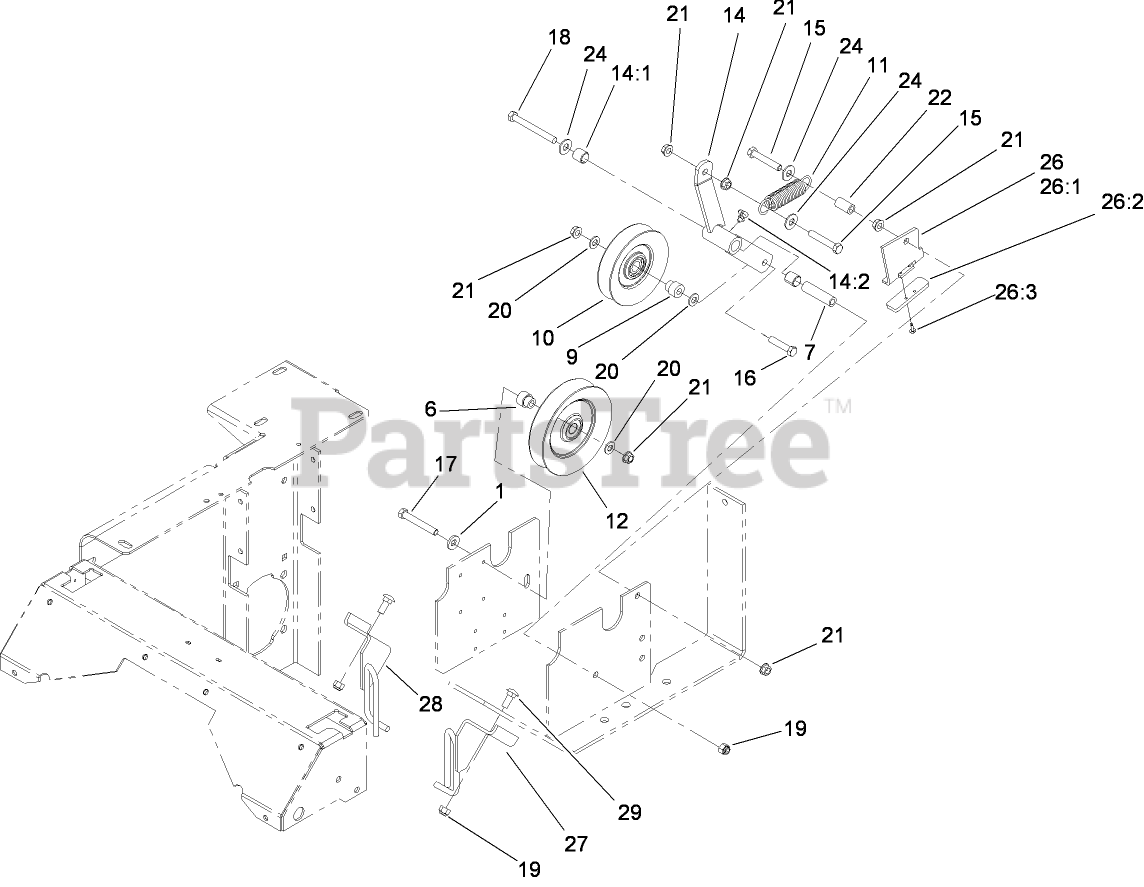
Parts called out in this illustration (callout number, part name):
1	WASHER-BELLEVILLE
6	Bushing-Idler
7	BUSHING-PIVOT, IDLER
9	BUSHING-IDLER
10	Idler
11	SPRING-EXTENSION
12	PULLEY-IDLER
14	Arm ASM
14:1	SLEEVE-BEARING
14:2	FITTING-GREASE, 90 DEG
15	SCREW-HH
16	SCREW-HH
17	SCREW-HH
18	SCREW-HH
19	NUT-LOCK, NI
20	WASHER-FLAT
21	NUT-HHF, WHIZ
22	SPACER
24	WASHER-FLAT
26	Travel Limiter ASM
26:1	Plate-Limiter, Pulley
26:2	PAD-BUMPER
26:3	RIVET
27	GUIDE-BELT, LH
28	GUIDE-BELT, RH
29	BOLT-CARR
